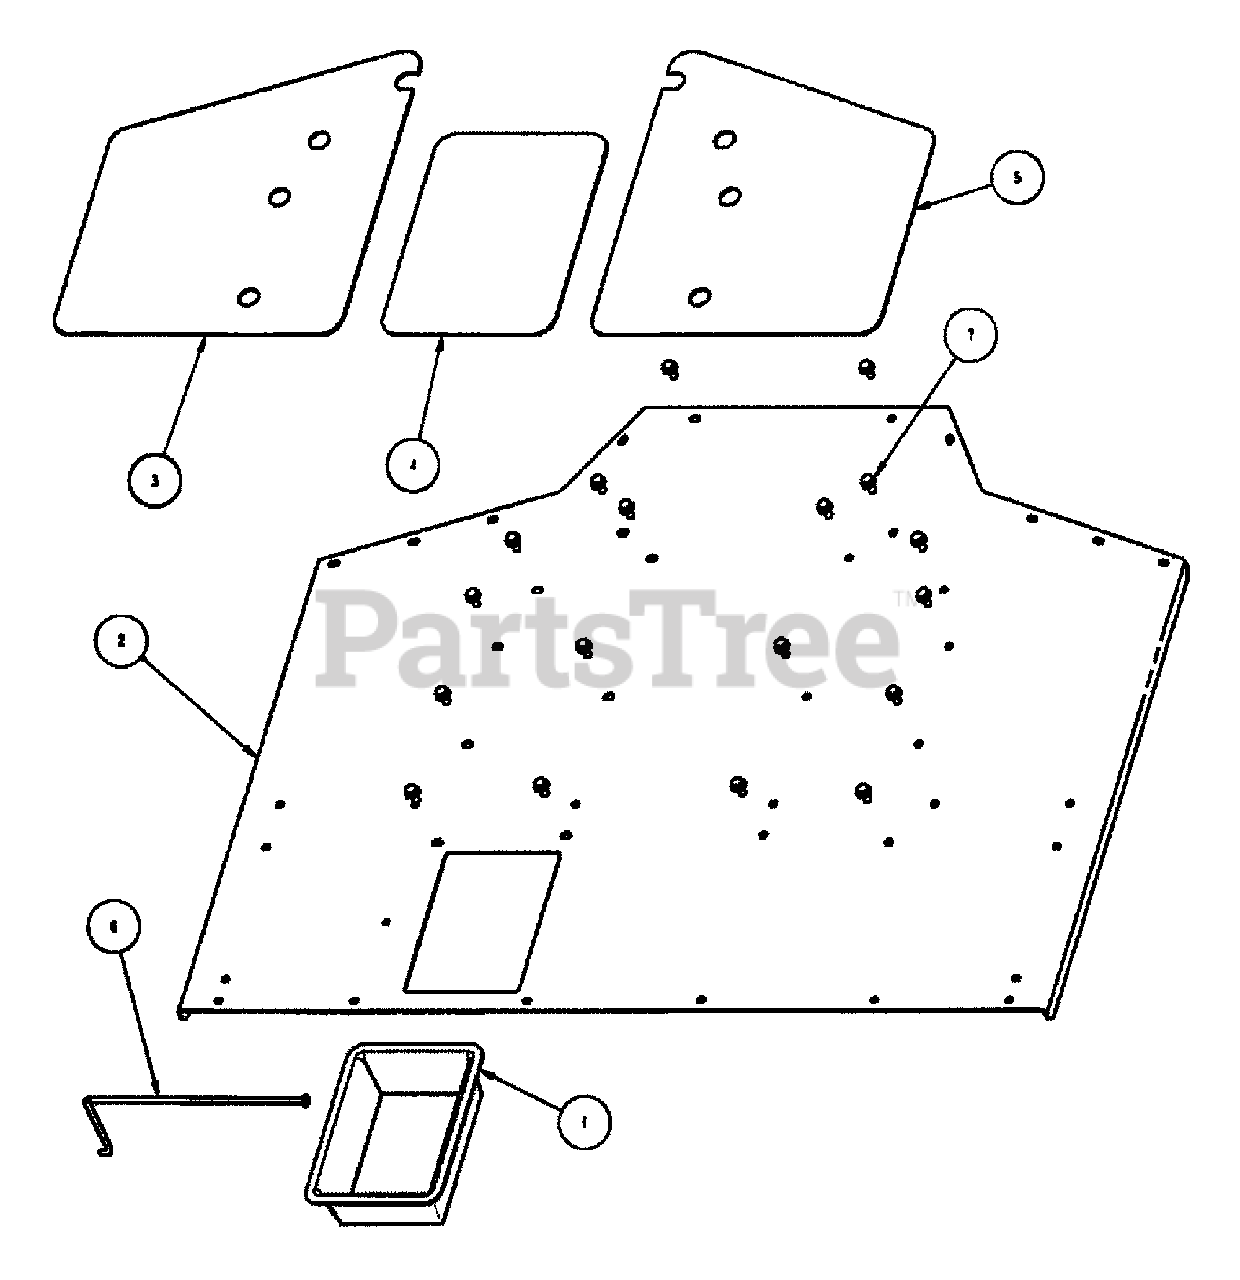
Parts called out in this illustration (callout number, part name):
1	TRAY, BATTERY
2	FLOORPAN
3	FOOTPAD,LH
4	FOOTPAD,CENTER
5	FOOTPAD,RH
6	BATTERY RETAINER
7	HFLB, 5/16-18 X .75 - YZ
